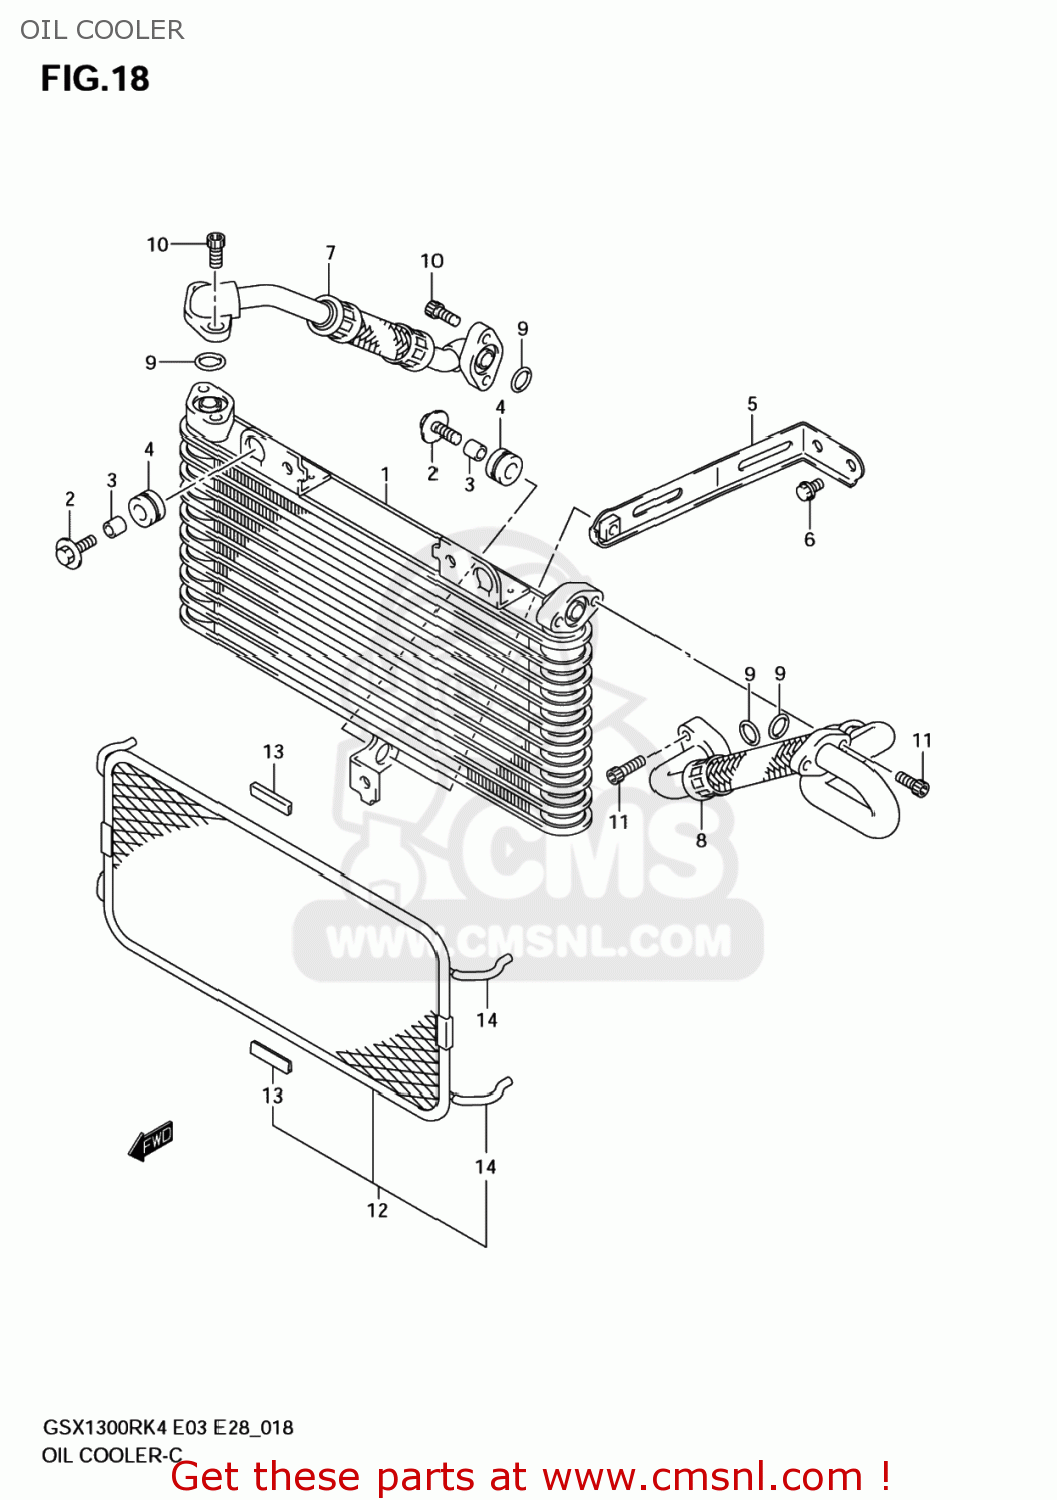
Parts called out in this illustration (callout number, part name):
1	COOLER ASSY,OIL
2	BOLT(6X20)
3	SPACER(6.5X10X10)
4	CUSHION
5	BRACKET,OIL COOLER
6	BOLT
7	HOSE,OIL COOLER,R
8	HOSE,OIL COOLER,L
9	O RING(D:2.4,ID:11.8)
10	BOLT(6X20)
11	BOLT(6X20)
12	GUARD,OIL COOLER
13	PROTECTOR,CTR
14	HOSE(3X5X600)
